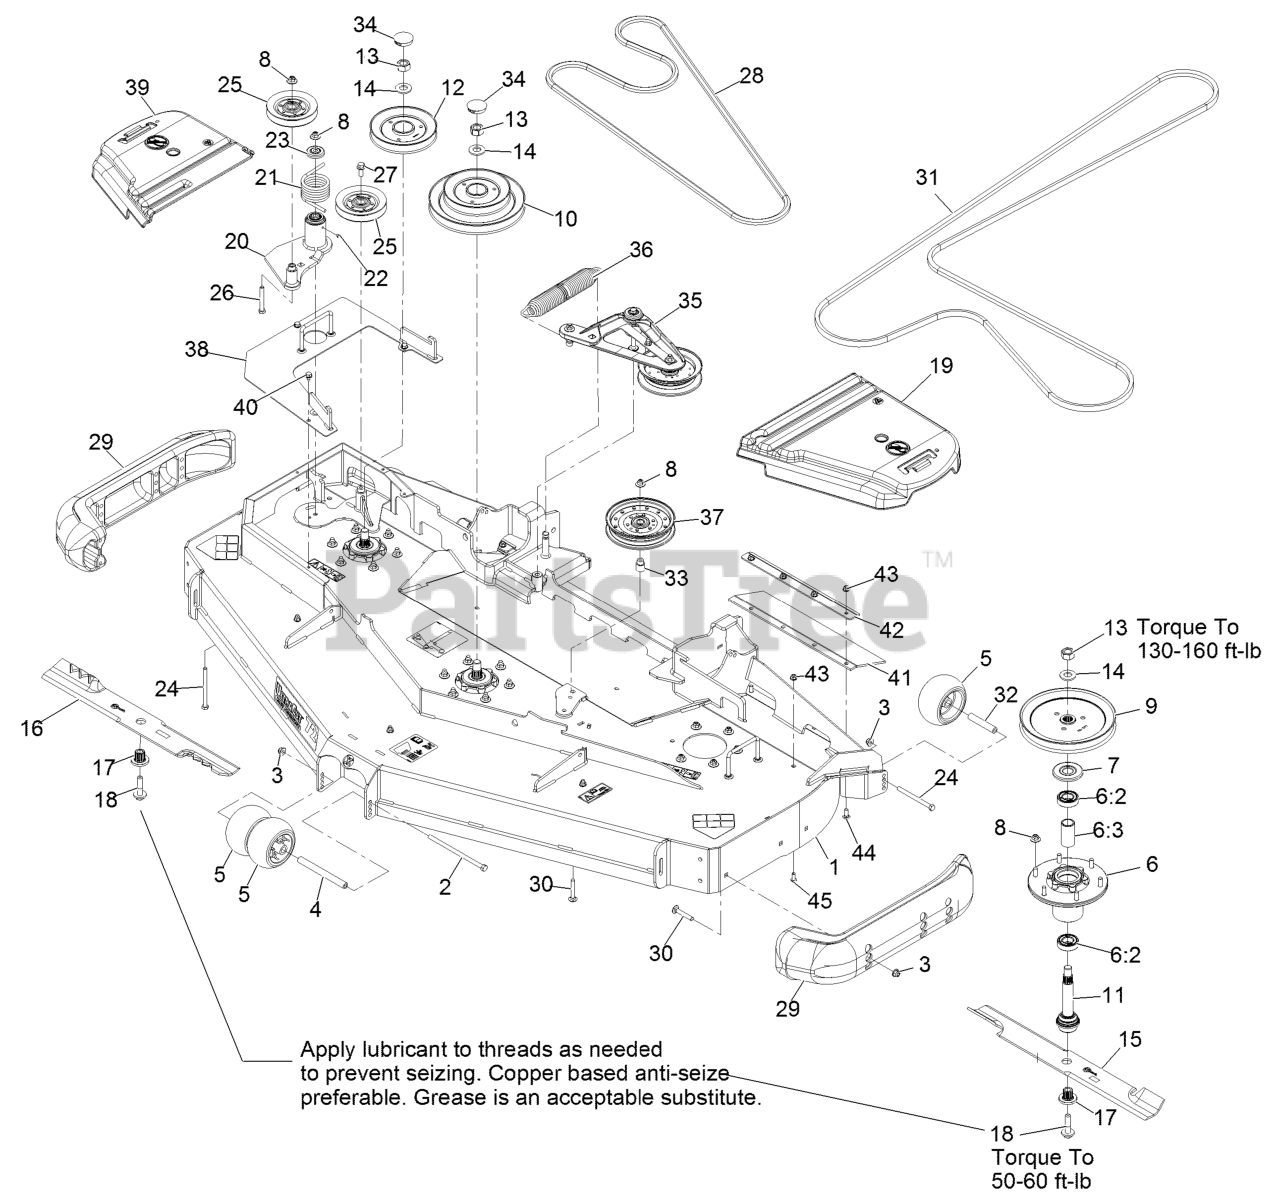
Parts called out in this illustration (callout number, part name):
1	DECK-RD72 NLZ, W/DECALS
2	SCREW-HH
3	NUT-HF, NI
4	SPACER-WHEEL
5	ROLLER-SCALP, ANTI
6	ASM-CUTTER HSG WITH BEARINGS
6:2	BEARING-BALL
6:3	SPACER-BEARING
7	GUARD,BEARING TOP .989
8	Nut-Nyloc 3/8-16 Flg
9	SHEAVE,BLADE DRIVE 8.74
10	SHEAVE, DOUBLE 72RD
11	ASM-SPINDLE AND SEAL
12	SHEAVE-RD REV DRIVE SERIE
13	NUT-HEX
17	BUSHING,SPLINED
18	SCREW,SEMS 1/2-20 X 2.19
19	COVER-BELT, LH
20	IDLER ASM
21	SPRING-TORSION
22	FITTING-GREASE
23	GUARD-TOP
24	SCREW-HH
26	SCREW-HH
27	SCREW-HHF
29	SKID-BUMPER, DECK
30	Bolt-Carriage 3/8-16 X 2 1/4
31	BELT
32	TUBE-SPANNER
33	BUSHING-IDLER
34	PLUG,BLACK NYLON 1.75
35	DECK IDLER ASM
36	SPRING-EXTENSION
38	COVER-REVERSE DRIVE
39	COVER-BELT, RH
41	GUARD-TIRE
42	SUPPORT-OUTER FLAP
43	NUT-HF, NI
44	SCREW-CARR
45	SCREW-HSBH
